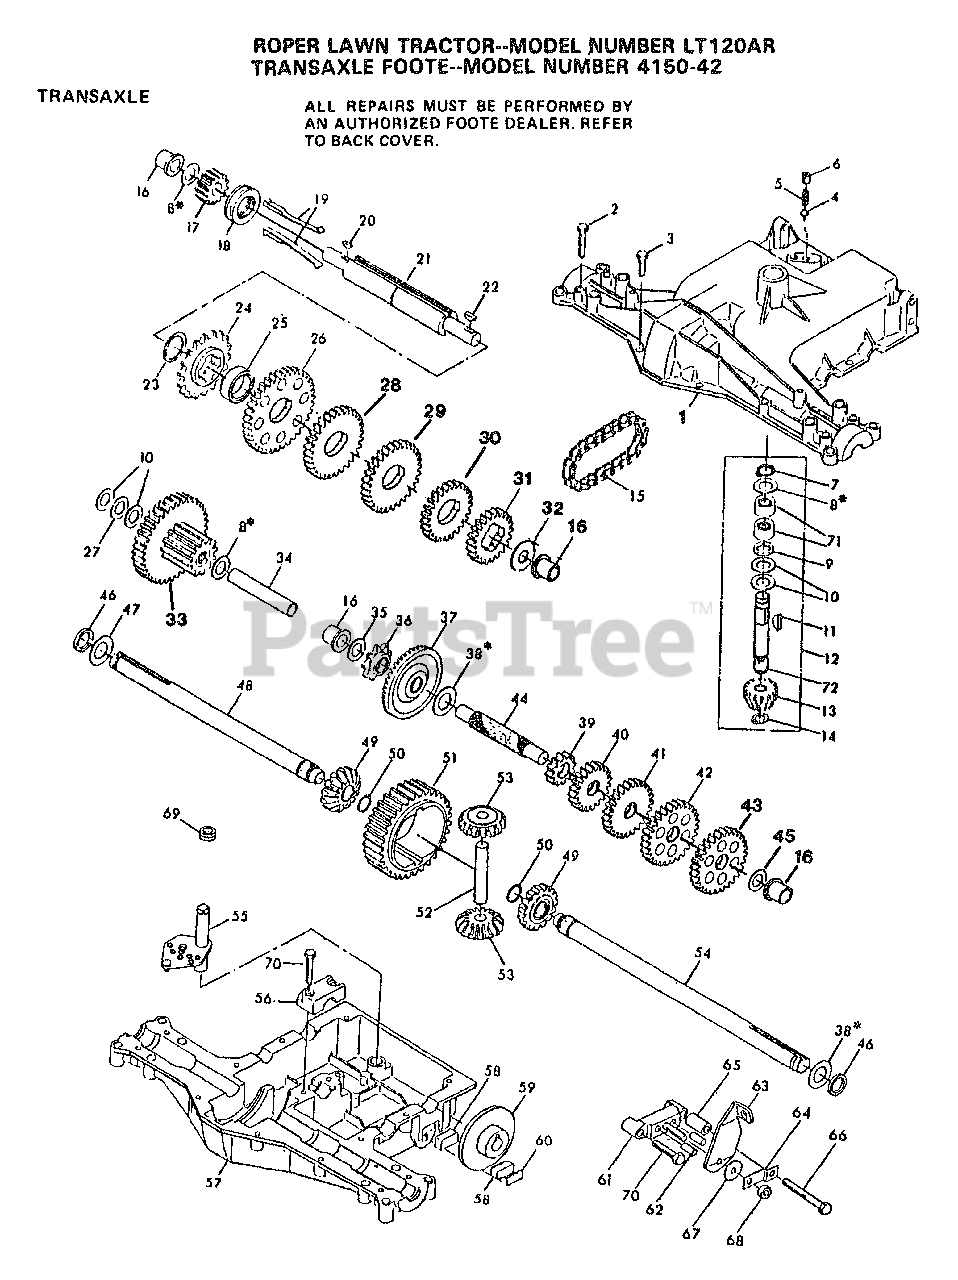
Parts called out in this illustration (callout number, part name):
1	HOUSING, UPPER
2	SCREW 1/4-20 X 1.31
3	SCREW 1/4-20 X .875
4	BALL DETENT
5	SPRING, DETENT
6	SCREW, SET
7	RING RETAINING
8	WASHER PLAIN
8	WASHER, PLAIN .632 X 1.00 X .026
8	WASHER, PLAIN .632 X 1.00 X .060
10	WASHER PLAIN
11	KEY WOODRUFF #9
12	ASSY KIT INPUT SHAFT
13	PINION, BEVEL, 14 TEETH
14	RING, RETAINING
15	CHAIN, 24 PITCHES
16	BEARING, FLANGE
17	GEAR SPUR, 14 TEETH
18	COLLAR CLUTCH
19	KEY, CLUTCH
20	KEY WOODRUFF #3
21	SHAFT, INTERMEDIATE
22	KEY, WOODRUFF, #61
23	RING, RETAINING
24	SPROCKET, 18T
26	GEAR, SPUR, 37 TEETH
27	SPACER .630 X 1.00 X .169
28	GEAR, SPUR 30T
29	GEAR, SPUR, 25 TEETH
30	GEAR, SPUR 22T
32	WASHER, PLAIN .640 X 1.37 X .061
33	ASSY GEAR COMB 12&35 TEETH
34	SHAFT, IDLER
35	WASHER PLAIN
36	SPROCKET, 9 TEETH
37	GEAR, BEVEL, 42 TEETH
38	WASHER PLAIN
38	WASHER, PLAIN .758 X 1.25 X .031
39	GEAR, SPUR, 12 TEETH
40	GEAR, SPUR 20T
41	GEAR, SPUR, 25 TEETH
42	GEAR, SPUR 28T
43	GEAR, SPUR, 31 TEETH
44	SHAFT, DRIVE
45	WASHER, PLAIN .632 X 1.00 X .060
47	WASHER, PLAIN .758 X 1.25 X .031
49	GEAR, MITER, 15 TEETH
50	RING, RETAINING
51	GEAR, SPUR, 32 TEETH
52	SHAFT, CROSS
53	GEAR, MITER, 15 TEETH
55	ASSY SHIFTER
56	CAP, SUPPORT
57	HOUSING, LOWER
58	PUCK, FRICTION
59	DISC, BRAKE
61	ASSY, JAW, BRAKE
62	PIN, DOWEL
63	LEVER, ACTUATING
64	BRKT, ANTI-ROTATION
66	SCREW 5/16-18 X 2.50
67	WASHER, PLAIN .321 X 1.00 X .055
68	LOCKNUT 5/16-24
70	SCREW TAPPING
